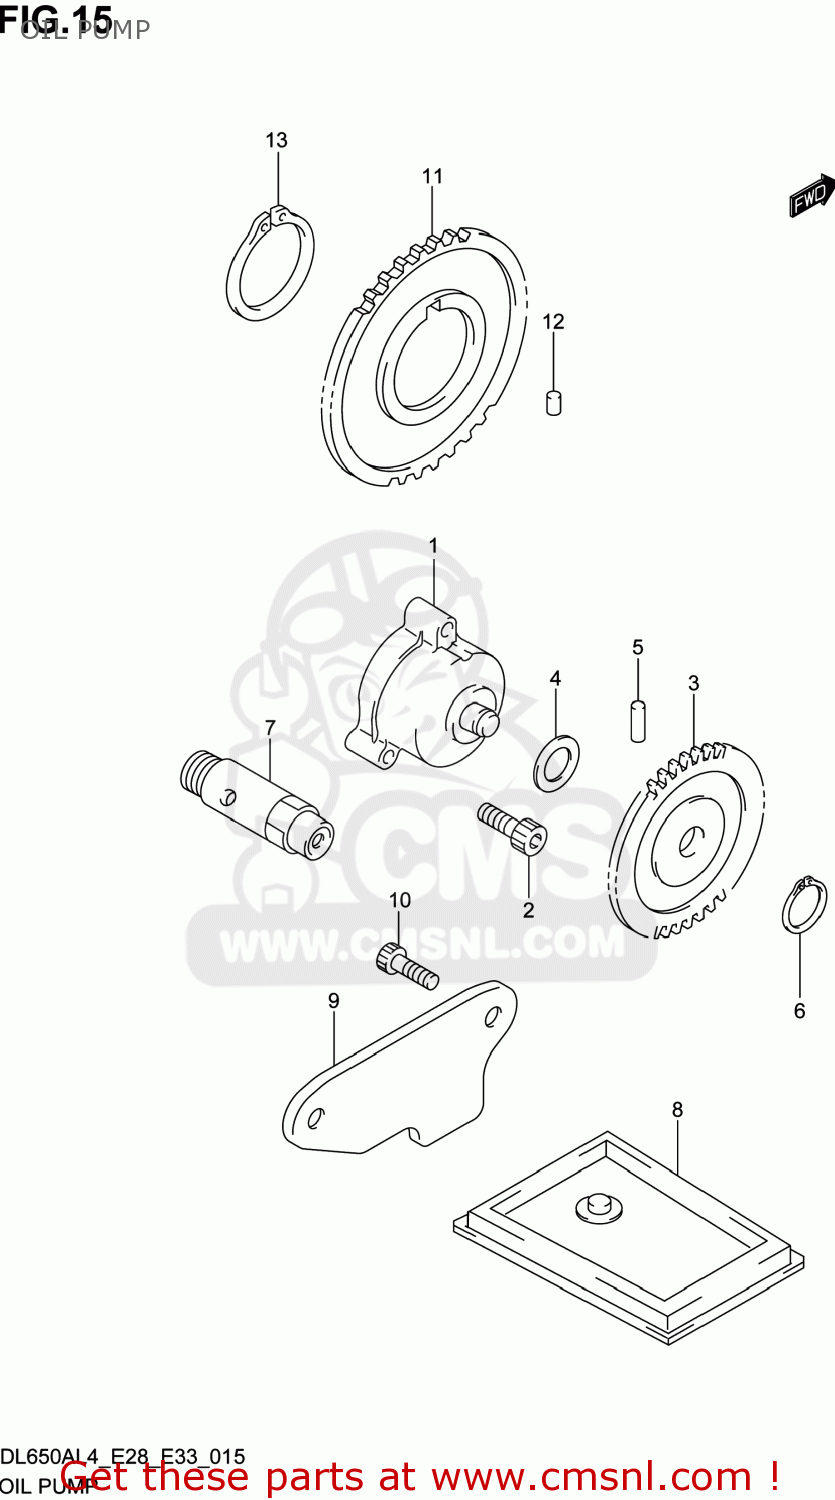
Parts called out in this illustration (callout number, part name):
1	PUMP ASSY,ENGINE OIL
2	BOLT
3	GEAR,ENG OIL PUMP DRIVEN
4	SHIM(10X18X0.5)
5	PIN(4X18.5)
6	CIRCLIP
7	VALVE ASSY,OIL RELIEF
8	STRAINER,ENGINE OIL
9	CAP,OIL STRAINER
10	BOLT
11	GEAR,ENG OIL PUMP DRIVE
12	PIN(6X6)
13	CIRCLIP
